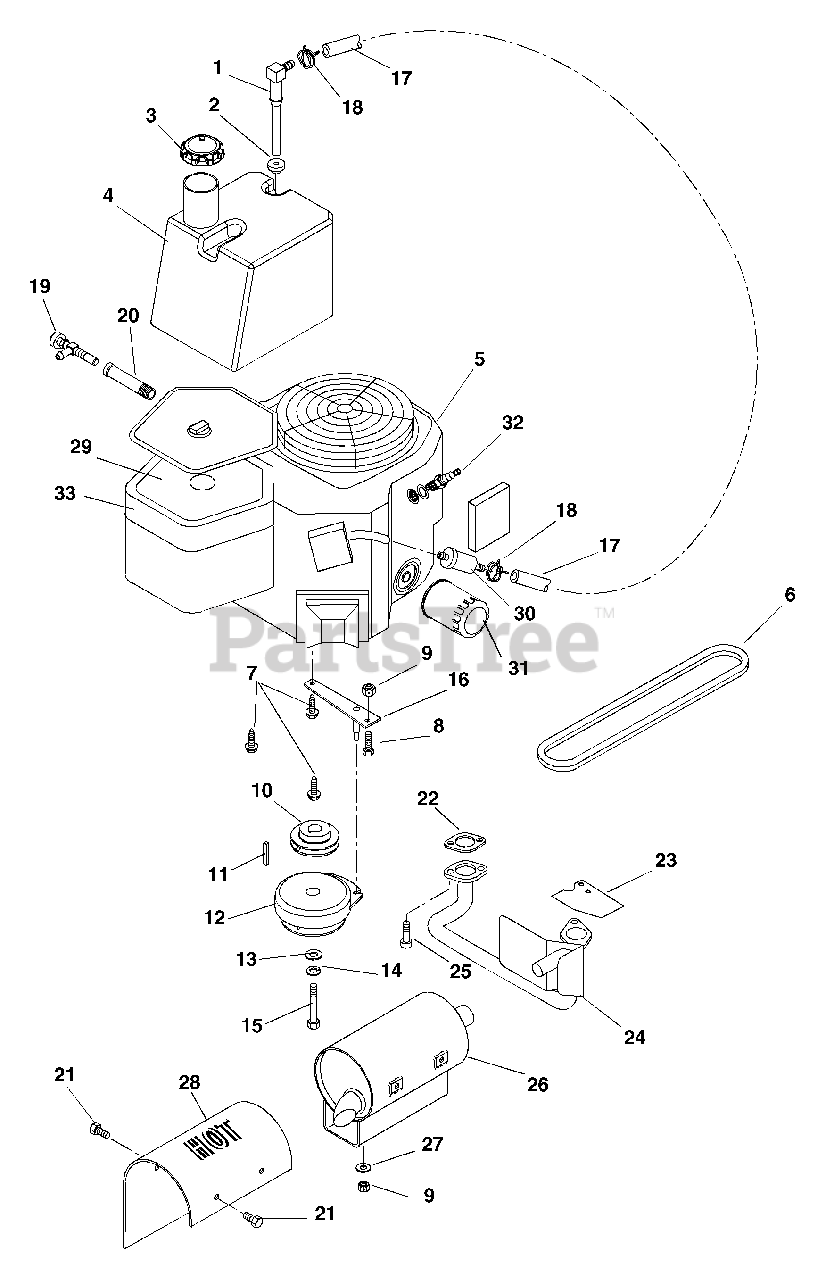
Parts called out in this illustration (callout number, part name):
1	Fitting, Tank
2	Bushing
3	Cap, Gas
4	Tank, Fuel
5	Engine, 25HP Kohler 6-Pin (018)
5	Engine, 23HP Kawasaki (020)
6	V-Belt A-Section 24.90 x .500 /.031
7	Screw-Tapping Hex-Washer-Head .38-16 x 1.00
8	Bolt-Hex .31-18 x 1.75 Grade 5
9	Nut-Locking-Center .31-18
10	Pulley-4.46 DIA x 1.12 Bore
11	Key-Square .25 x 1.00 x .25
12	Electric Clutch
13	Washer-Flat-Steel .515 x 1.625 x .250
14	Washer-Locking .44 x .109
15	Bolt-Hex .44-20 x 3.00 Grade 5
16	Anchor-Clutch
17	Gas Line-Bulk 1/4" ID
18	Hose-Clamp
19	Nipple,Pipe .38 x 6.00 Unfinished Steel
20	Pipe Cap
21	Bolt, Hex M5 - .8 x 8 mm
22	Gasket-Exhaust (018)
23	Heat Deflector (018)
24	Manifold-Kohler CV18-25 (018)
24	Manifold-Kawasaki, PM310 (020)
25	Screw-Socket Head M8-1.25 x 20 mm
26	Muffler (Includes 09066300 Heat Shield)
27	Washer, Flat-Steel
28	Heat Shield (Included with 09065600 Muffler)
29	Air Filter (018)
29	Air Filter (020)
30	Fuel Filter
31	Filter, Oil- Kohler CV20 (018)
31	Filter, Oil- Kawasaki (020)
32	Spark Plug (018)
32	Spark Plug (020)
33	Element, Precleaner (018)
33	Element, Precleaner (020)
